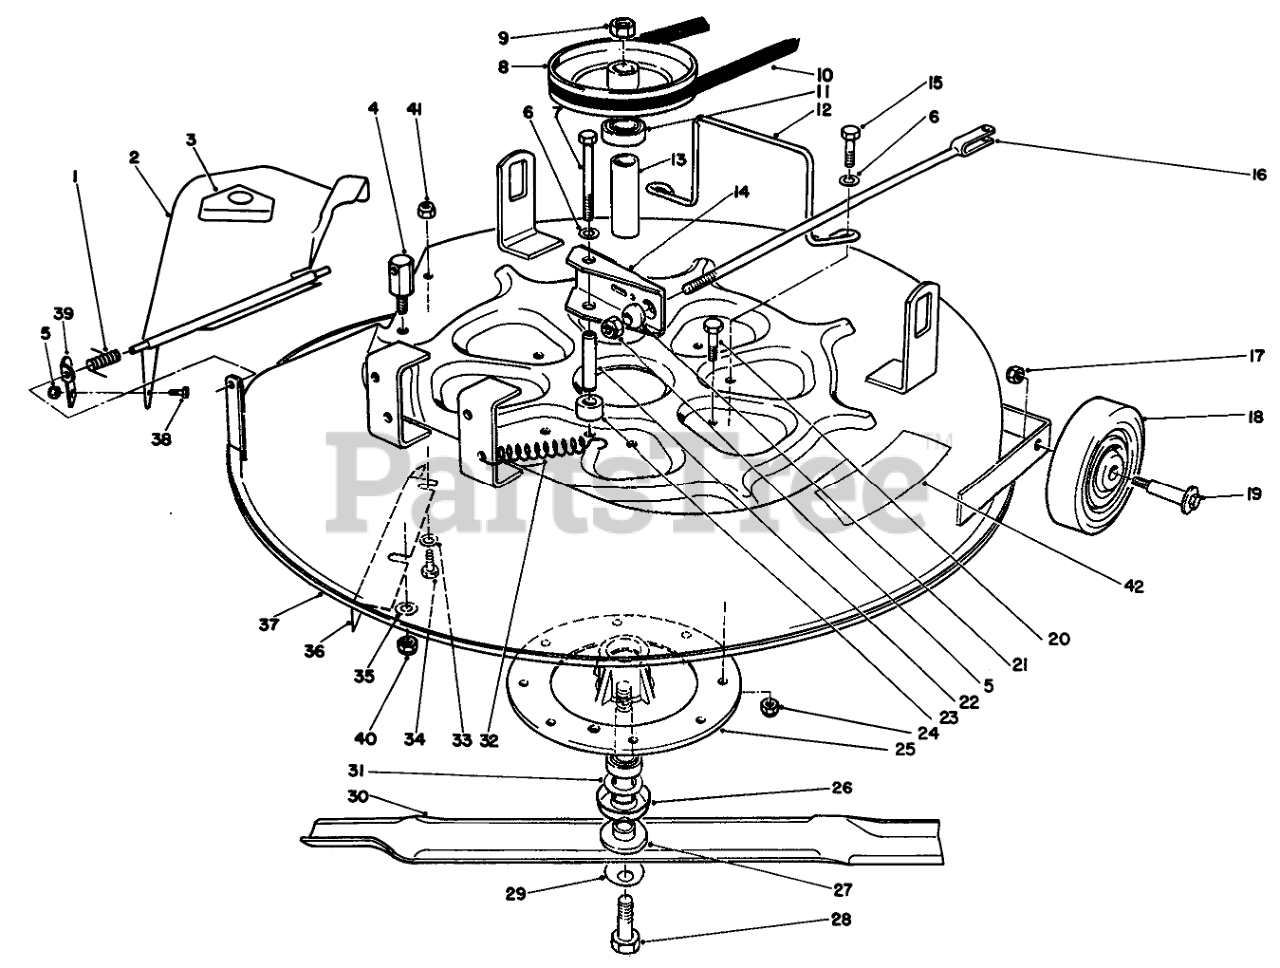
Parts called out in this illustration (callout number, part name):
1	SPRING
2	Deflector (Incl. Ref. #3)
3	DECAL-DANGER
4	POST-PIVOT
5	NUT-HEX
6	WASHER-PLAIN
7	SCREW-HH
8	PULLEY-DECK
9	NUT-HEX
10	V-Belt
11	BEARING-BALL
12	GUIDE-DECK BELT
13	SPACER-BEARING
14	DECK BRAKE ASSEMBLY
15	SCREW-HH
16	DECK BRAKE ROD WA
17	NUT-LOCK, NI
18	WHEEL-DECK
19	BOLT-WHEEL
20	SCREW-HH
21	BALL-SWIVEL, STOP
22	POST-BRAKE MTG
23	SPACER-DECK BRAKE
24	NUT-LOCK, NI
25	CASTING-SPINDLE
26	SHIELD-BEARING
27	SHAFT-SPINDLE
28	SCREW-HH
29	WASHER-BELLEVILLE
30	Blade
31	SPACER
32	SPRING-EXTENSION
33	WASHER-FLAT
34	SCREW-HHF
35	WASHER-FLAT
36	Baffle
37	Deck
38	SCREW-HH
39	Bracket-Detector
40	NUT-LOCK, NI
41	NUT-LOCK, NI
42	DECAL - DANGER
